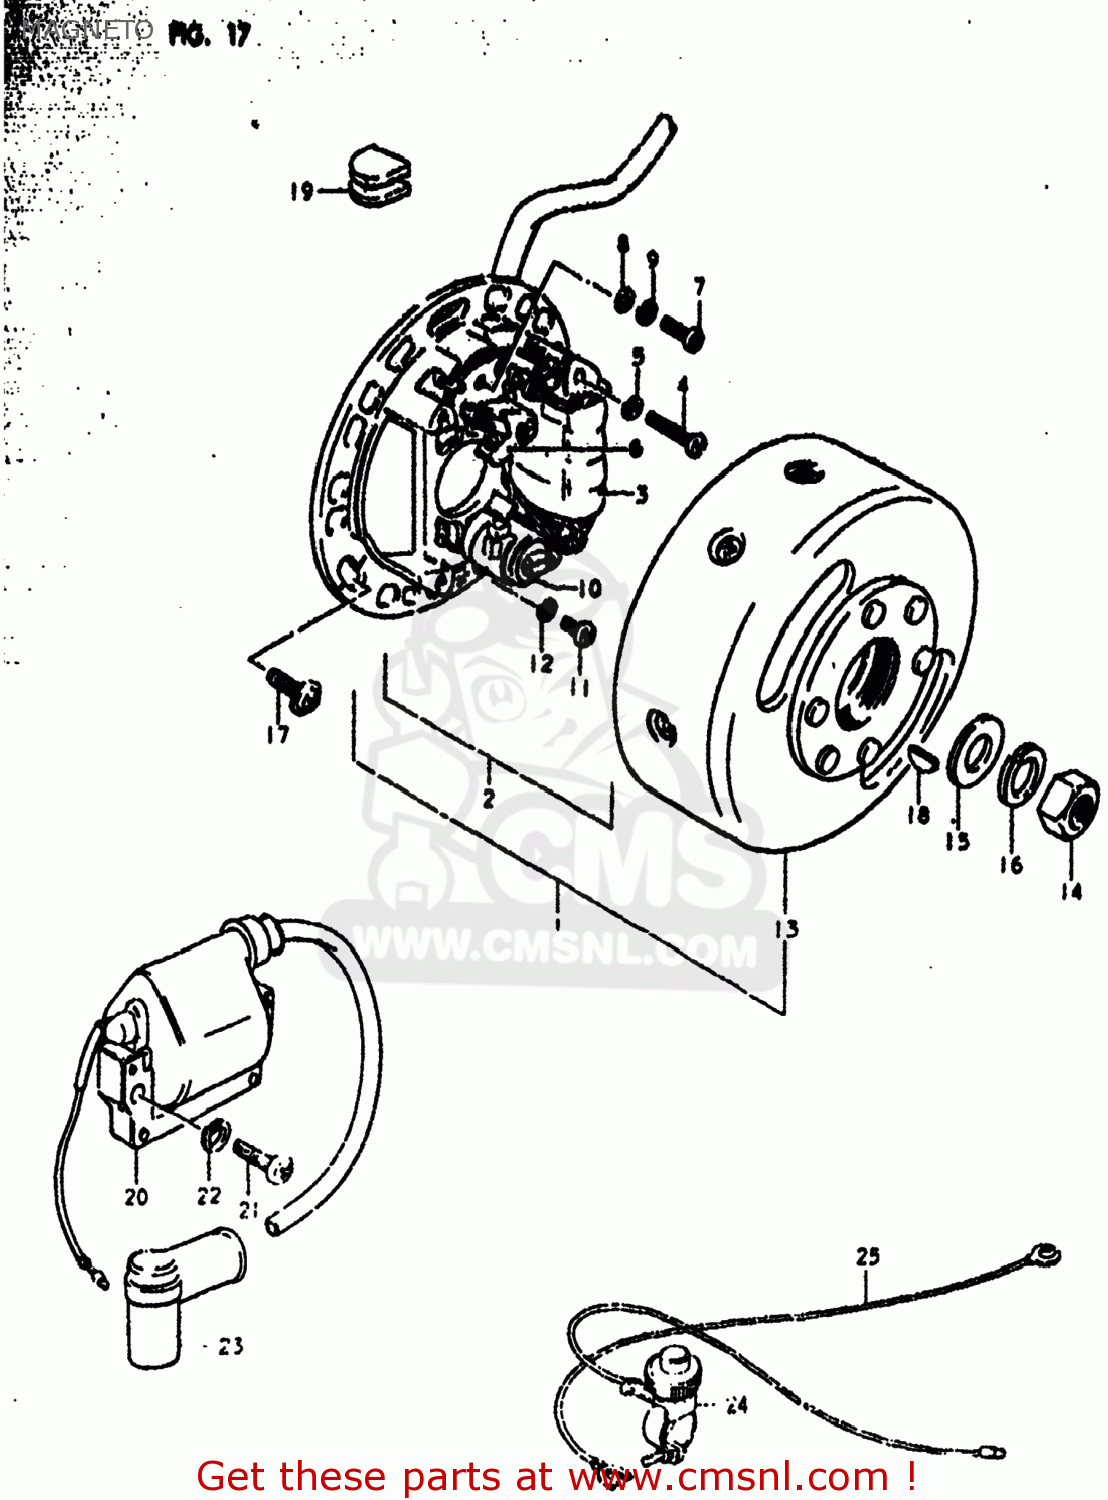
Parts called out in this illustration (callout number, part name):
1	MAGNETO ASSEMBLY
2	STATOR ASSEMBLY
3	COIL,PRIMARY
4	SCREW (4X30)
5	LOCK WASHER
6	POINT ASSY,CONTACT
7	SCREW(4X10)
8	WASHER
9	LOCK WASHER
10	CONDENSER
11	SCREW
12	LOCK WASHER
13	ROTOR ASSEMBLY
14	NUT (10MM)
15	WASHER
16	LOCK WASHER
17	SCREW(5X14)
18	KEY
19	PLUG
20	COIL ASSEMBLY,IGNITION
21	SCREW
22	LOCK WASHER
23	CAP,SPARK PLUG
24	SWITCH ASSEMBLY
25	WIRE,ENGINE STOP EARTH
